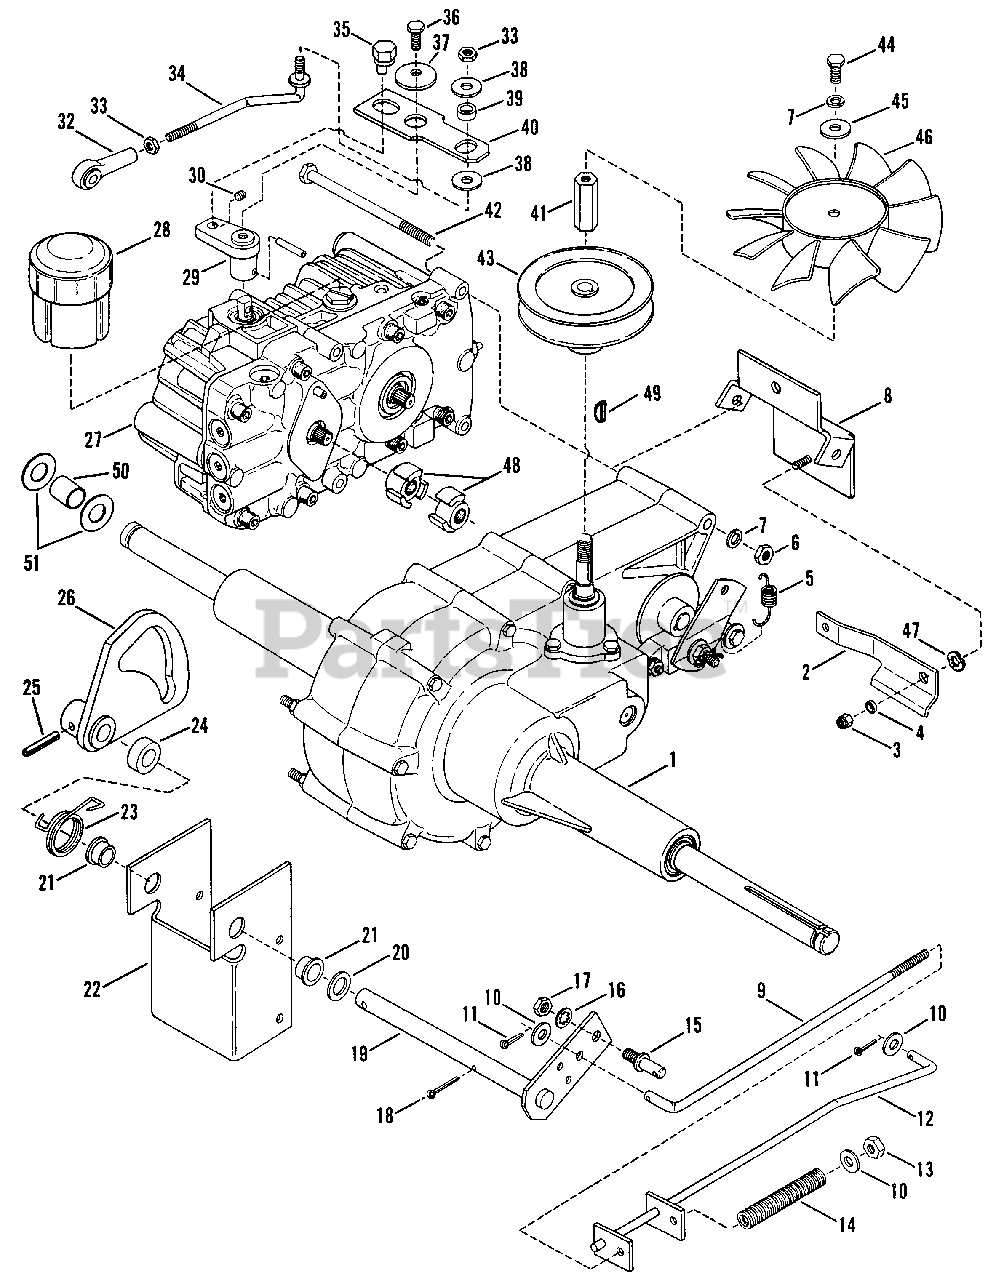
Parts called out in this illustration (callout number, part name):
1	TRANSAXLE ASSEMBLY
2	LEVER, Release
3	NUT, 1/4-20 Hex Lock
4	SPACER .37 OD x .271 ID x .120 L
5	SPRING, Brake Return
6	NUT, 5/16-18 Hex
7	WASHER, 5/16 Split Lock
8	TORQUE BRACKET ASSEMBLY
9	ROD, Brake Spring
10	WASHER 5/16 x 7/8 x .083
11	COTTER-PIN, 5/32 x 1"
12	ROD, Brake Stop
13	NUT, 5/16-18 Hex Center Lock
14	SPRING, Brake
15	STUD, Neutral Pivot
16	WASHER, 3/8 Internal Tooth Lock
17	NUT, 3/8-24 Hex
18	COTTER-PIN,1/8 x 1 1/4"
19	NEUTRAL PIVOT ASSEMBLY
20	WASHER
21	BEARING, 5/8 Flanged Nylon .625 ID x .719 x .325 (No longer available)
22	SUPPORT, Neutral Pivot
23	SPRING, Torsion
24	SPACER, 1.120 OD x .635 ID x .38 L (No longer available)
25	PIN, Roll, 1/4 x 1 1/4"
26	CAM, Neutral Return
27	TRANSMISSION, Hydro (HG BDU-105-120)
28	RESERVOIR ASSEMBLY (HG 2003081)
29	HUB, Speed Control
30	SCREW, 1/4-28, 1/8 Hex Socket Set (No longer available, try using 7077667)
31	PIN, Spiral 5 MM x 36 MM
32	BALL JOINT, 5/16-24
33	NUT, 5/16-24 Hex
34	ROD, Adjustment 4.41" l, 5/16-24 Ends (No longer available)
35	PIN, Eccentric
36	SCREW, 5/16-18 x 1/2" Hex Head Cap
37	WASHER, Cone .32 x 1.4 x .1
38	WASHER, Flat .327 x .875 x .09
39	ROLLER
40	PLATE, Speed Control
41	NUT, Special 3/4 Hex Stock/5/16-24 Thru/9/16-18x1.0 Deep (No longer available)
42	SCREW, 5/16-18 x 4 1/2" Hex Head Cap
43	PULLEY, Drive
44	SCREW, 5/16-24 x 1/2" Hex Head Cap
45	WASHER, Fender 5/16
46	FAN, 7" DIA 10 Blade
47	WASHER, 3/8 Wave
48	PUMP COUPLING
49	KEY, 3/32" X 5/8" Hi-pro
50	SPACER 1.25 OD x .791 ID x 1.115 L
51	WASHER, 3/4" Flat
